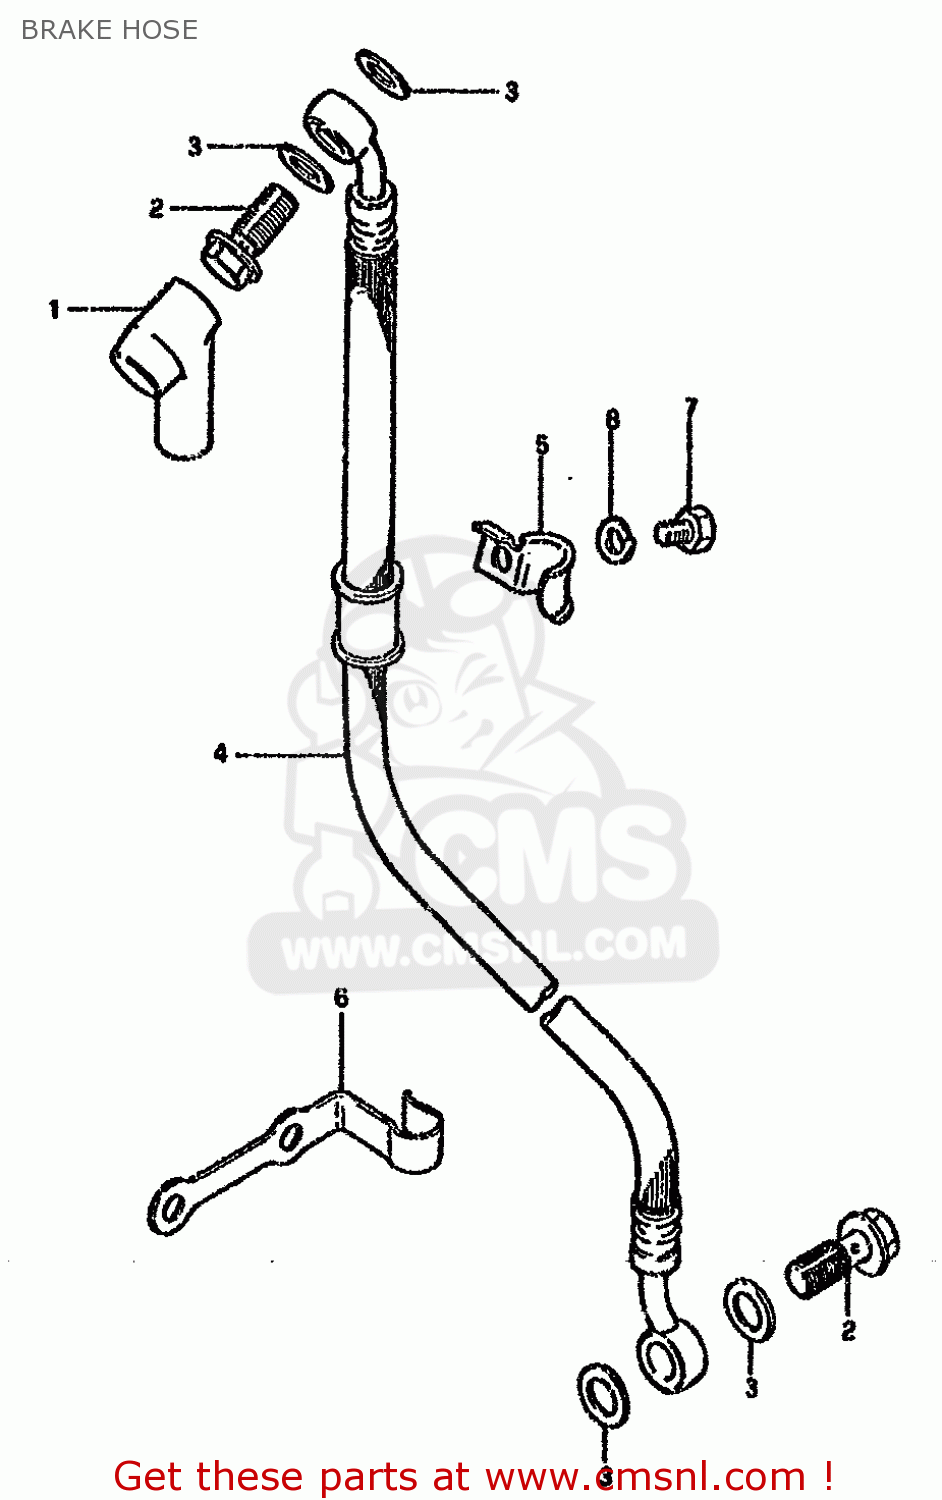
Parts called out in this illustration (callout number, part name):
1	BOOT,MASTER CYLINDER
2	BOLT UNION
3	WASHER(10X15X1.5)
4	HOSE,FR BRAKE
5	CLAMP,BRAKE HOSE
6	CLAMP,BRAKE HOSE
7	BOLT
8	WASHER,LOCK
